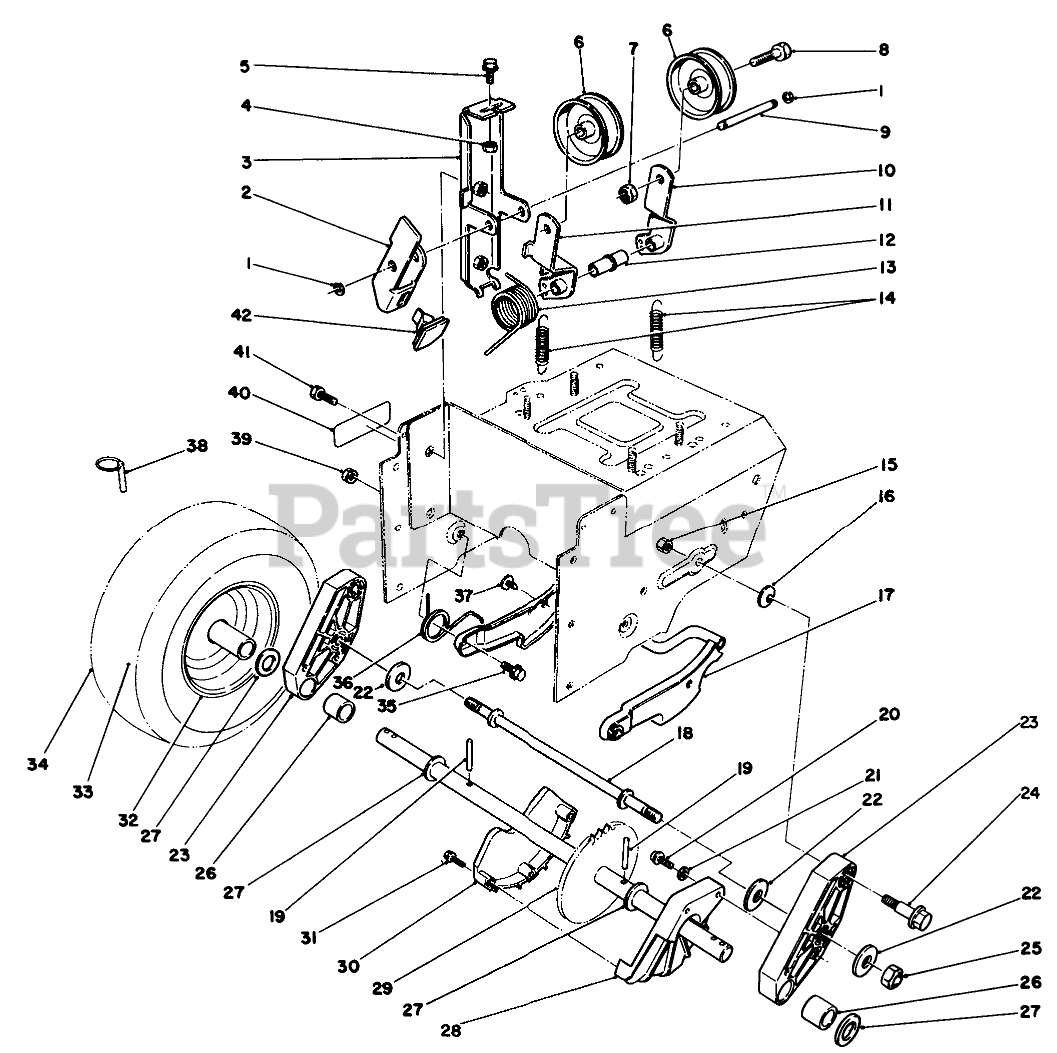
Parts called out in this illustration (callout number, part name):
1	RING-RETAINING
2	ARM-BRAKE
3	IDLER ARM BRACKET ASM
4	NUT-LOCK, NI
5	SCREW-HHF
6	PULLEY-IDLER
7	NUT-LOCK, NI
8	SCREW-HH
9	PIN-IDLER
10	ARM-IDLER, TRACTION
11	ARM-IDLER, IMPELLER
12	BUSHING-IDLER
13	SPRING-TORSION
14	SPRING-EXTENSION
15	NUT-LOCK, NI
16	WASHER-SPRING
17	Latch-Arm
18	ROD-LATCH
19	PIN-ROLL, SLOTTED
20	SCREW-HWH
21	WASHER-FLAT
22	WASHER-SUPPORT
23	Pivot Arm Assembly (Incl. Ref. #26)
24	BOLT-SHOULDER
25	NUT-LOCK, NI
26	BUSHING-AXLE
27	WASHER-THRUST
28	GUARD-CHAIN, LH
29	AXLE ASM
30	GUARD-CHAIN, RH
31	SCREW-PPH
32	WHEEL
33	TUBE-INNER
35	SCREW-SHOULDER
36	SPRING-LATCH, TORSION
37	FASTENER-PANEL
38	PIN-LYNCH
39	NUT-LOCK, NI
40	DECAL-WARNING
41	SCREW-HHF
42	PAD-BRAKE
